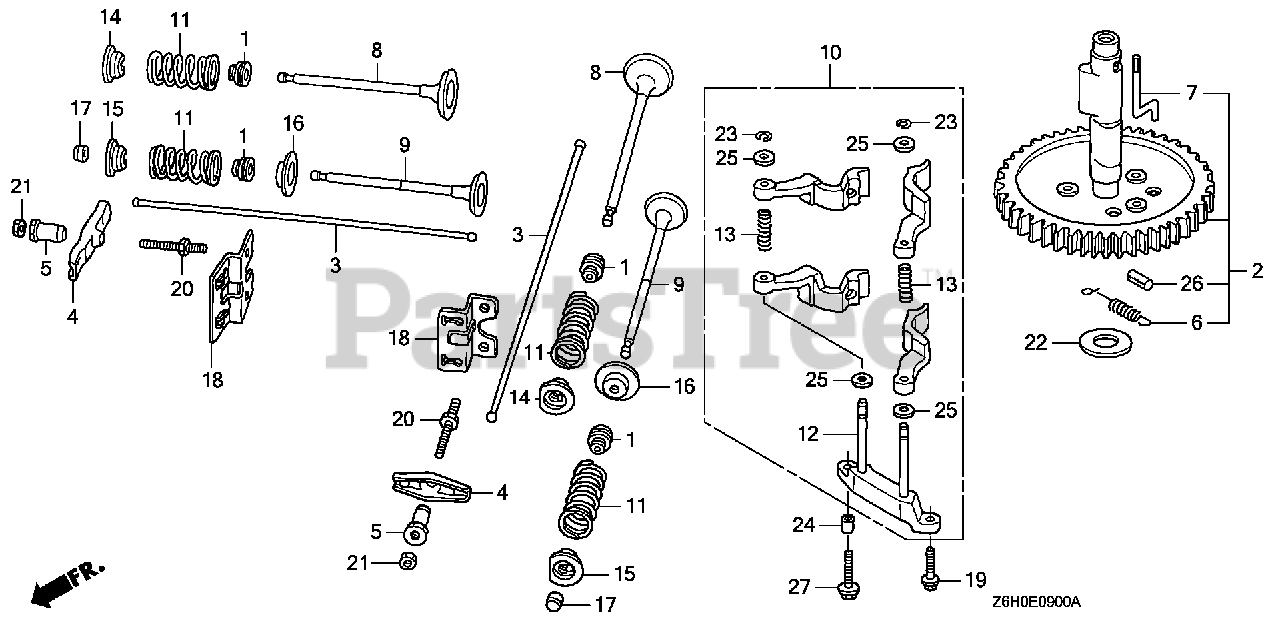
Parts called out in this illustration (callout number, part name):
1	SEAL, VALVE STEM
2	CAMSHAFT ASSY.
4	ARM, VALVE ROCKER
5	PIVOT, ROCKER ARM
6	SPRING, WEIGHT RETURN
7	PIN, DECOMPRESSION
8	VALVE, IN.
9	VALVE, EX.
10	LIFTER ASSY., VALVE
11	SPRING, VALVE
12	SHAFT, VALVE LIFTER
13	SPRING, VALVE LIFTER
14	RETAINER, IN. VALVE SPRING
15	RETAINER, EX. VALVE SPRING
16	SEAT, VALVE SPRING
17	ROTATOR, VALVE
18	GUIDE, PUSH ROD
19	BOLT, FLANGE (5X16)
20	BOLT, PIVOT (8MM)
21	NUT, PIVOT ADJUSTING
22	WASHER, THRUST (17.2MM)
23	CLIP, GOVERNOR HOLDER
24	PIN A, DOWEL (8X12)
25	WASHER, PLAIN (6MM)
26	PIN, SPRING (6X28)
27	BOLT, FLANGE (6X25)
